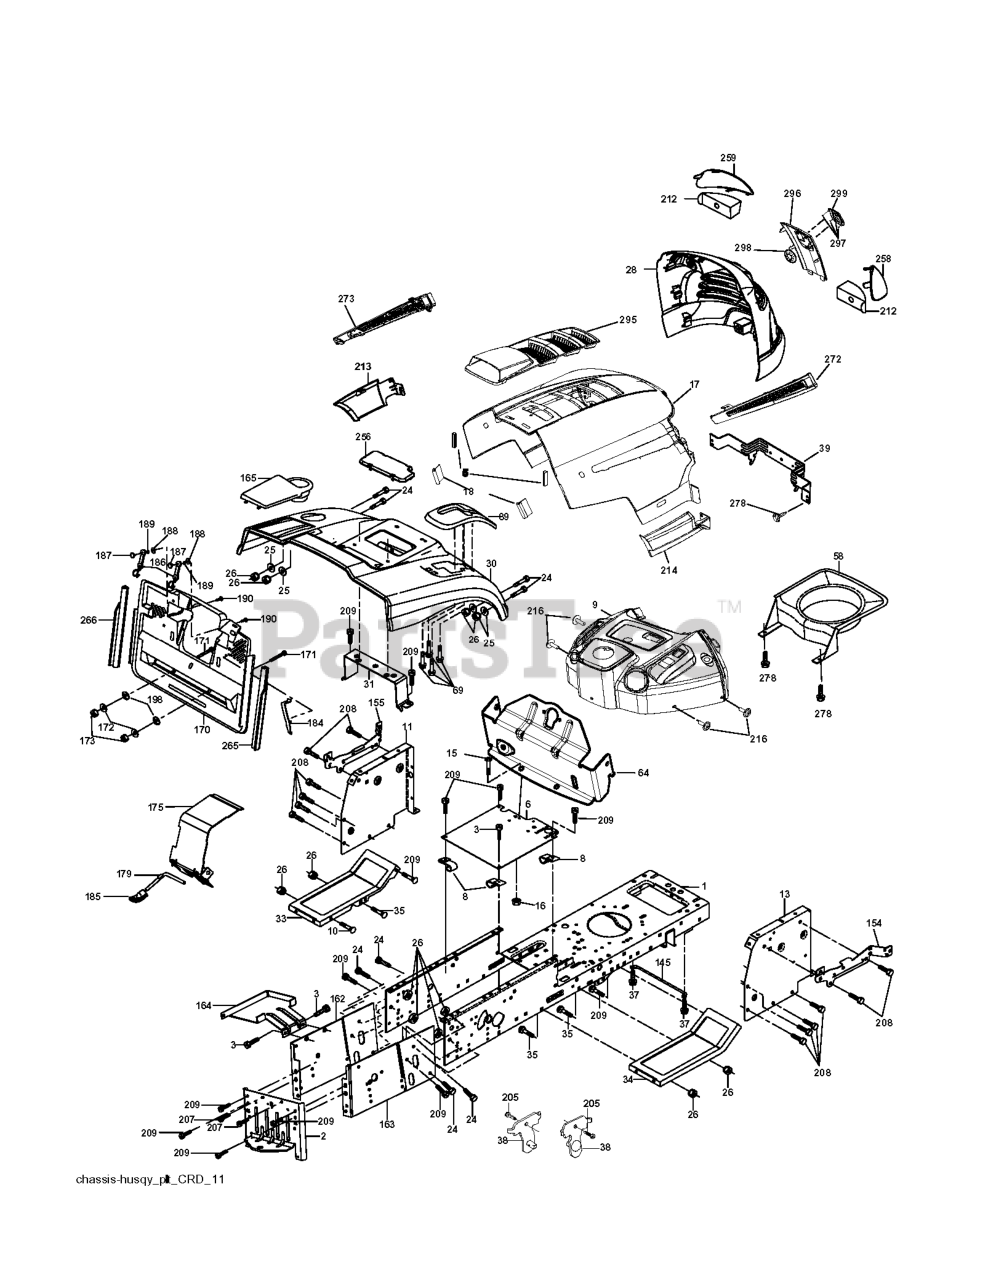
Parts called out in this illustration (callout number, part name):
2	DRAWBAR
3	SCREW 3/8-16X3/4
5	BUMPER DASH
6	PLATE
8	CLIP,INSULATOR
10	BOLT D
11	PANEL.DASH.LH.LTX
13	PANEL ASM, DASH RH
15	Screw, Machine, Truss Head 5/16-18 UNC x 3/4
16	NUT
17	HOOD
18	BUMPER.HOOD.TEX.HUSQVARNA
25	WASHER
26	NUT
28	RP GRILLE/LENS ASM.
30	CONSOLE.CRD.AUTO.GRY
31	BRACKET SUPPORT FENDER
33	FOOTREST PNT LH
34	FOOTREST PNT RH
37	Screw 5/16-18 x 1/2 Hex, Self Tapping 5/16-18 x 1/2
38	BRACKET ASM PIVOT MOWER REAR
39	BRACKET PIVOT
69	SCREW.HI-LO.CONSOLE
89	CONSOLE.CRD.AUTO.GREY.2005
145	ROD PIVOT CHASSIS/HOOD
162	BRACKET
163	BRACKET EXTEN CHASSIS RH CRD
165	RP.COVER.BATTERY.CRD.GREY
172	WASHER
175	DOOR TRAP
179	ROD PIVOT FBI
184	BRACKET.ACTUATOR.BAGGER.SRD
186	LATCH ASSY
187	WELDNUT
189	LOCKWASHER #10
190	SCREW
207	SCREW, 5/16-18 X 1/2
208	SCREW 3/8-16X1/2
209	SCREW, 3/8-16X3/4
212	INSERT REFLECTIVE
213	SKIRT SIDE LH
214	SKIRT SIDE RH
216	SCREW HEXWSHR 1/4-20X3/4
256	COVER FENDER CRD
258	LENS.HUSQVARNA LT.RH
259	LENS.HUSQVARNA LT.RH
265	SEALING
266	SEALING
278	SCREW
295	VENT TOP HOOD
296	TRIM
297	CLIP.RETAINER.TINNER.
298	NUT PUSH M
299	RP LOGO
